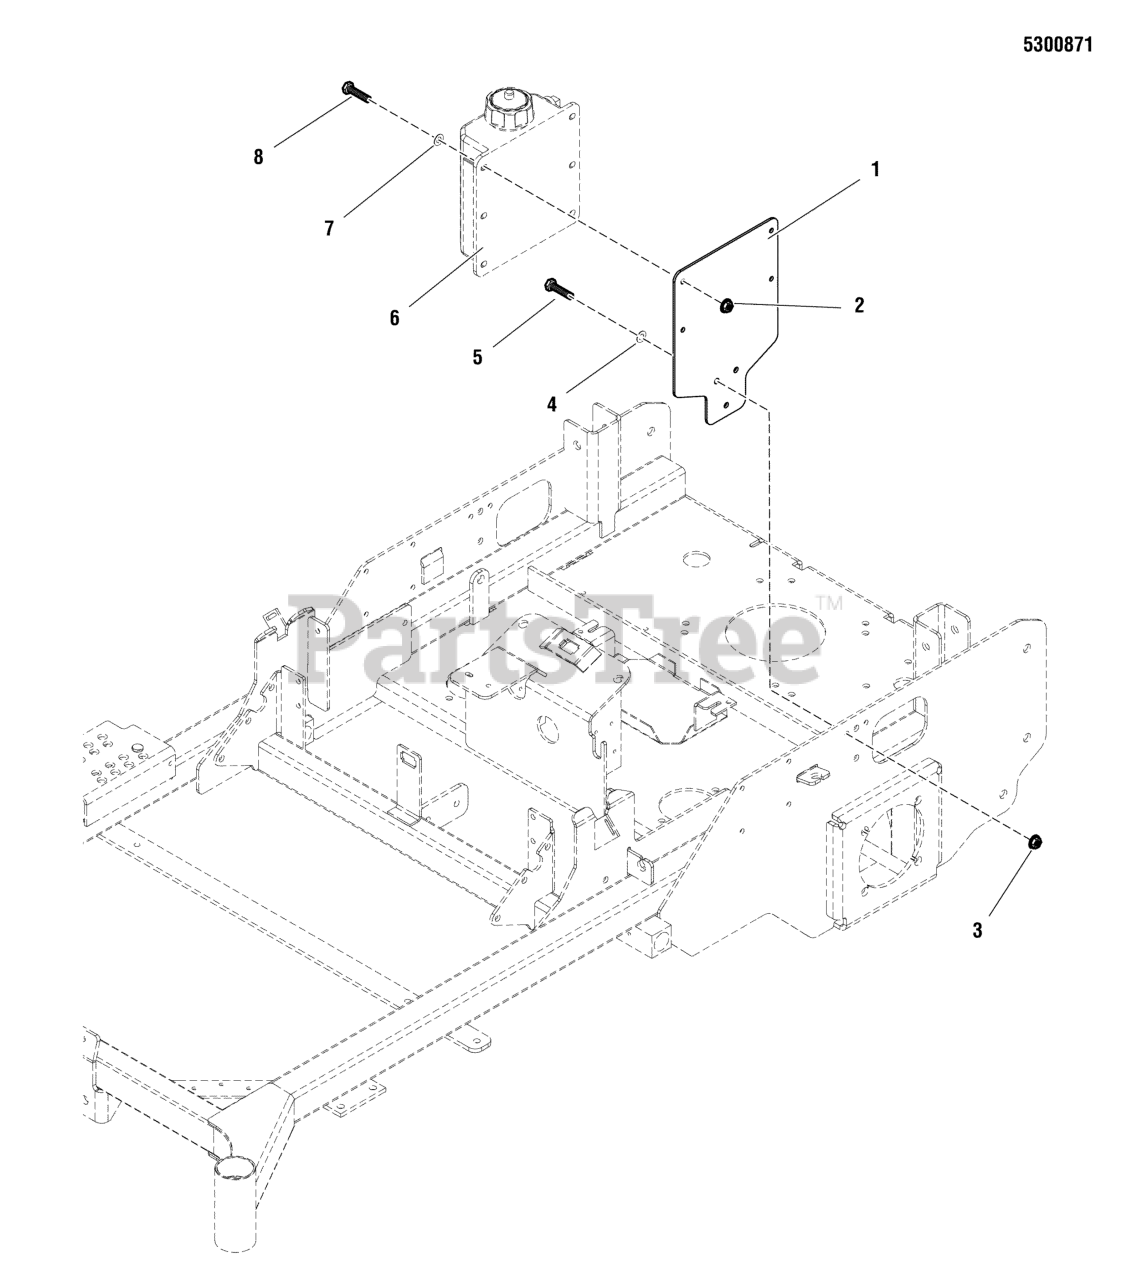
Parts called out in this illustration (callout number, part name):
1	PLATE, HYDRAULIC TANK MOUNT - RED
2	NUT, 1/4-20 HEX NYLOCK FLANGE
3	NUT, 5/16-18 HEX NYLOCK FLANGE
4	WASHER, 5/16" SAE
5	BOLT, 5/16-18 X 1 GD5 YZ
6	TANK, HYDRAULIC (SEE HYDRAULIC GROUP)
7	WASHER, 1/4 SAE
8	BOLT, 1/4-20 X 1" GD5 CZ
